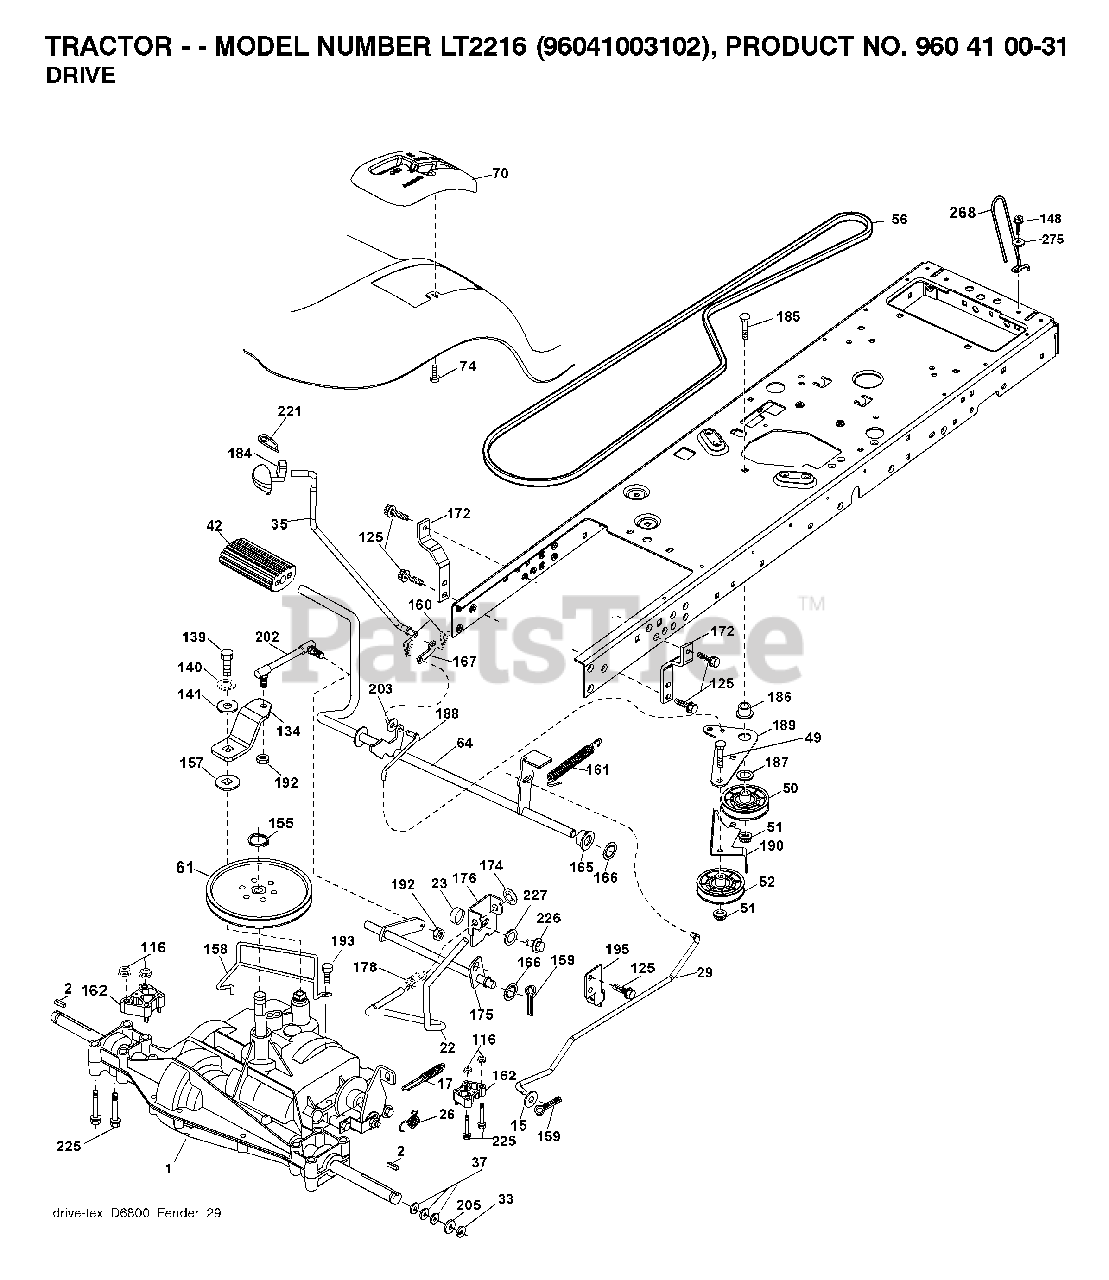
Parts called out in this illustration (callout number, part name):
2	SQUARE KEY
17	SPRING.BRAKE.PEERLESS.TEX
22	ROD.SHIFT.FENDER.TLT.2006
23	KNOB.DUCKHEAD.1/2
26	SPRING.BRAKE.RTN.GR.DR
29	ROD.BRAKE.PEERLESS
33	E-RING LT
35	ROD.BRAKE.PARKING.LT.T
42	PEDAL COVER T
49	BOLT
50	IDLER.FLAT.910.OFFSET
51	NUT LOCK FLG 3/8-16 UNC
52	IDLER.V-GROOVE.910.OFFSET
61	PULLEY TRANS
64	SHAFT.ASM.PEDAL.BRAKE.
70	CONSOLE.SHIFT.
74	SCREW.HI-LO.CONSOLE
116	NUT LOCK HEX FLANGE 5/16-18
125	SCREW
134	ARM.SHIFT.
139	BOLT 1/4-28X3/4
140	LOCKWASHER
141	WASHER LT
148	SCREW, 3/8-16X3/4
155	RETAINING RING LT
157	WASH-SHFT PLT LT
158	KEEPER.PMS.18/20.D4365
159	COTTER PIN
160	RETAINER CLIP
161	SPRING.RETURN.CLUTCH.2006
162	SPACER.TRANSAXLE.18&22
165	BUSHING.SHAFT.BRAKE.HAND
166	NUT.PUSH.625.2006
167	LATCH.BRAKE.SPRING
172	STRAP.TRQ.LH.GEAR.DRIV
174	NUT.PUSH.500.2006
175	SHAFT.ASM.SHIFT.
176	ARM.CLEVIS.ROD.SHIFT
178	SPRING.SHIFT.GT2006
184	HANDLE.PAKRING.BRAKE.
186	SPACER.RETAINER
187	WASHER 12/32X2X10GA
188	LINK.CLUTCH.GROUND.DRIVE
189	BELLCRANK.GROUND.DRIVE.TEX.
190	KEEPER.BELLCRANK.DRIVE
192	NUT LOCK CENTER 1/4 -28 FNTHD
193	SCREW 5/16"
195	BRKT.ROD.BRAKE.PEERLES
202	LINK.TRANSAXLE.
203	WASHER
221	RETAINER.SPRING.CLIP.H
225	BOLT.HEX.FLNG.5/16-18X3.75
226	BOLT FIN HEX 7/16-14 X 1
227	WASHER SERRATED
268	WASHER
